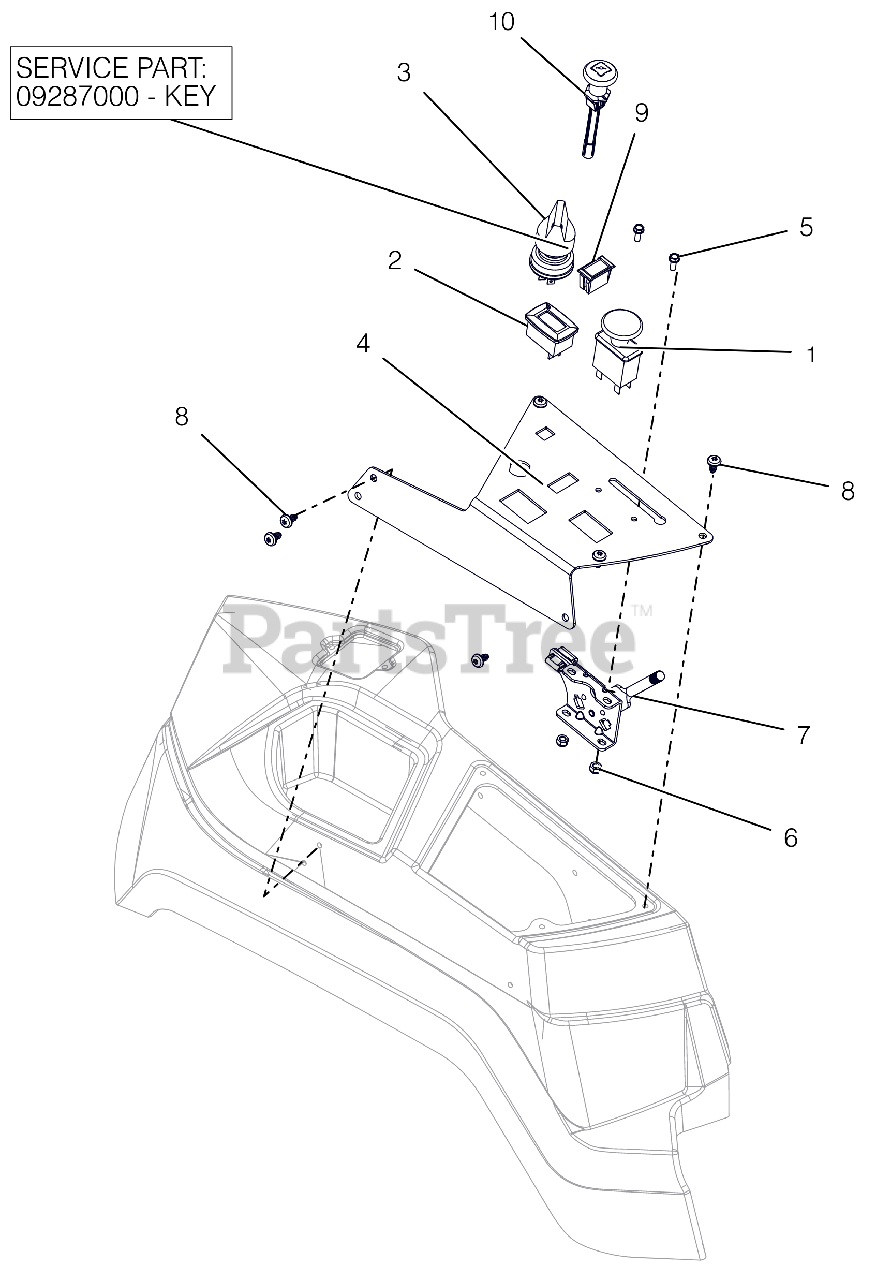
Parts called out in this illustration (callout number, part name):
1	SWITCH, CLUTCH
2	METER, HOUR W/MAINTENANCE
3	SWITCH, IGNITION
3	KEY, W/ SHIELD
4	PLATE, APEX CONTROL PANEL
5	@SCR-MCH 10-24X.50 HWH YWZC
6	@NUT-LK-NYL 10-24 W/INSRT YWZC
7	CABLE, PRO THROTTLE CONTROL
8	SCR-PAN .25-15X.50 6L H/LZB500
9	SWITCH,BLANK
10	CABLE - CHOKE, SNAP-IN
